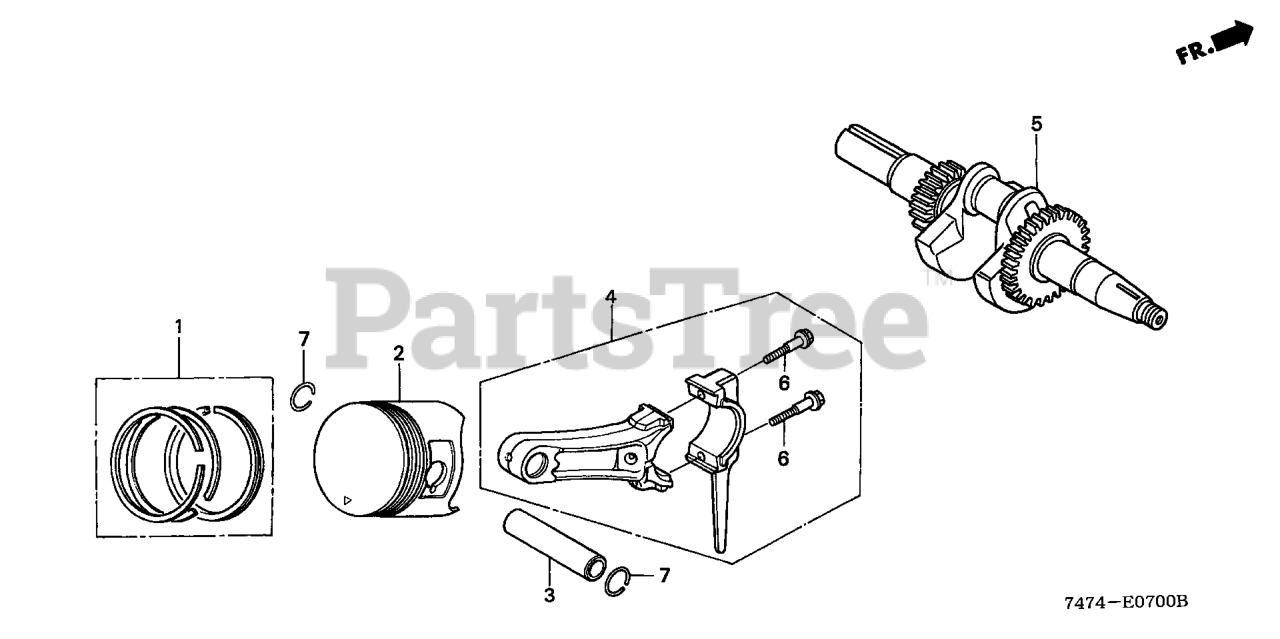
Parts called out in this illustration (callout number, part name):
1	RING SET, PISTON (STD) (TEIKOKU)
1	RING SET, PISTON (STD.) (NIPPON)
1	RING SET, PISTON (OS 0.25) Use from Engine SN 7603339.
1	RING SET, PISTON (0.25) (NIPPON) Use up to Engine SN 1314912.
1	RING SET, PISTON (OS 0.50) Use from Engine SN 7603339.
1	RING SET, PISTON (0.50) (NIPPON) Use up to Engine SN 1314912.
1	RING SET, PISTON (0.75) (TEIKOKU) Use up to Engine SN 1314912.
1	RING SET, PISTON (0.75) (NIPPON) Use up to Engine SN 1314912.
2	PISTON (STD)
2	PISTON (OS 0.25)
2	PISTON (OS 0.50)
2	PISTON (0.75)
3	PIN, PISTON
4	ROD ASSY., CONNECTING (0.25 LOWER SIZE) (NOT AVAILABLE)
4	ROD ASSY., CONNECTING
5	CRANKSHAFT
6	BOLT, CONNECTING ROD
7	CLIP, PISTON PIN (18MM)
